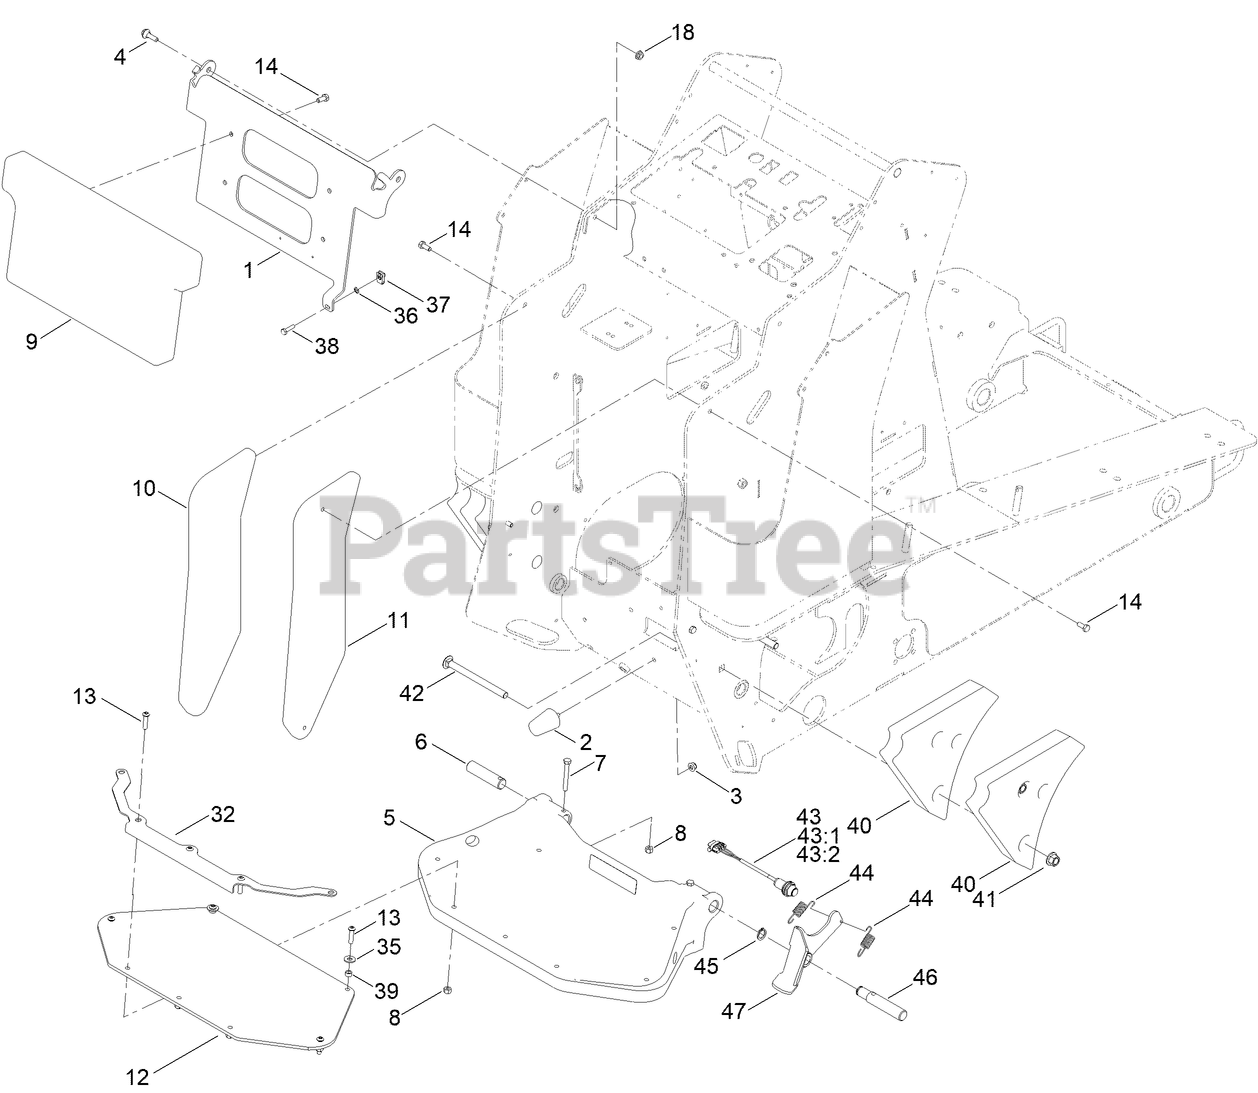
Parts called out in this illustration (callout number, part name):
1	HINGE-PAD
2	BUMPER
3	NUT-HF, NI
4	SCREW-SHOULDER
5	PLATFORM
6	PIN-PIVOT
7	SCREW-HH
8	NUT-LOCK, NI
9	CUSHION-PAD
10	CUSHION-PAD
11	CUSHION-PAD
12	PAD-FOOT
13	SCREW-HSBH
14	SCREW-HH
18	NUT-HF
32	PLATE - CLAMP
35	WASHER-FLAT
36	NUT-RETAINING
38	SCREW-HH
39	SPACER-PIVOT, TILT
40	PLATE, WEIGHT
41	NUT-LOCK
42	SCREW-CARR
43	PROXIMITY SWITCH ASM
43:1	NUT-HEX
43:2	WASHER-LOCK, INTERNAL TOOTH
44	SPRING-EXTENSION
45	RING-RETAINING
46	PIN-PLATFORM
47	PEDAL ASM
